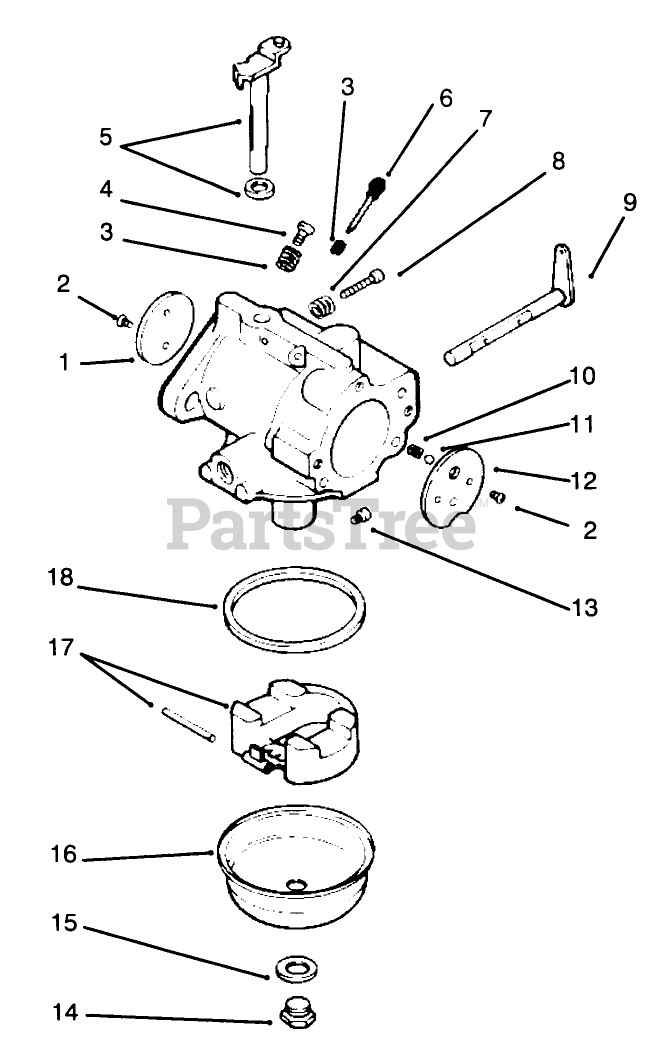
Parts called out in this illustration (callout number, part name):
1	Plate-Throttle
2	Screw
3	Spring
4	Needle-Idle Fuel Adj.
5	Shaft-Throttle
6	Needle-Main Fuel
7	Spring
8	Needle-Main Fuel
9	Lever-Choke
10	Spring-Choke Friction
11	Ball-Choke Friction
12	Plate-Choke
13	Jet-Main
14	Screw-Bowl Retainer
15	Gasket-Retainer Screw
16	Bowl-Fuel
17	Kit-Float
18	Gasket-Bowl
